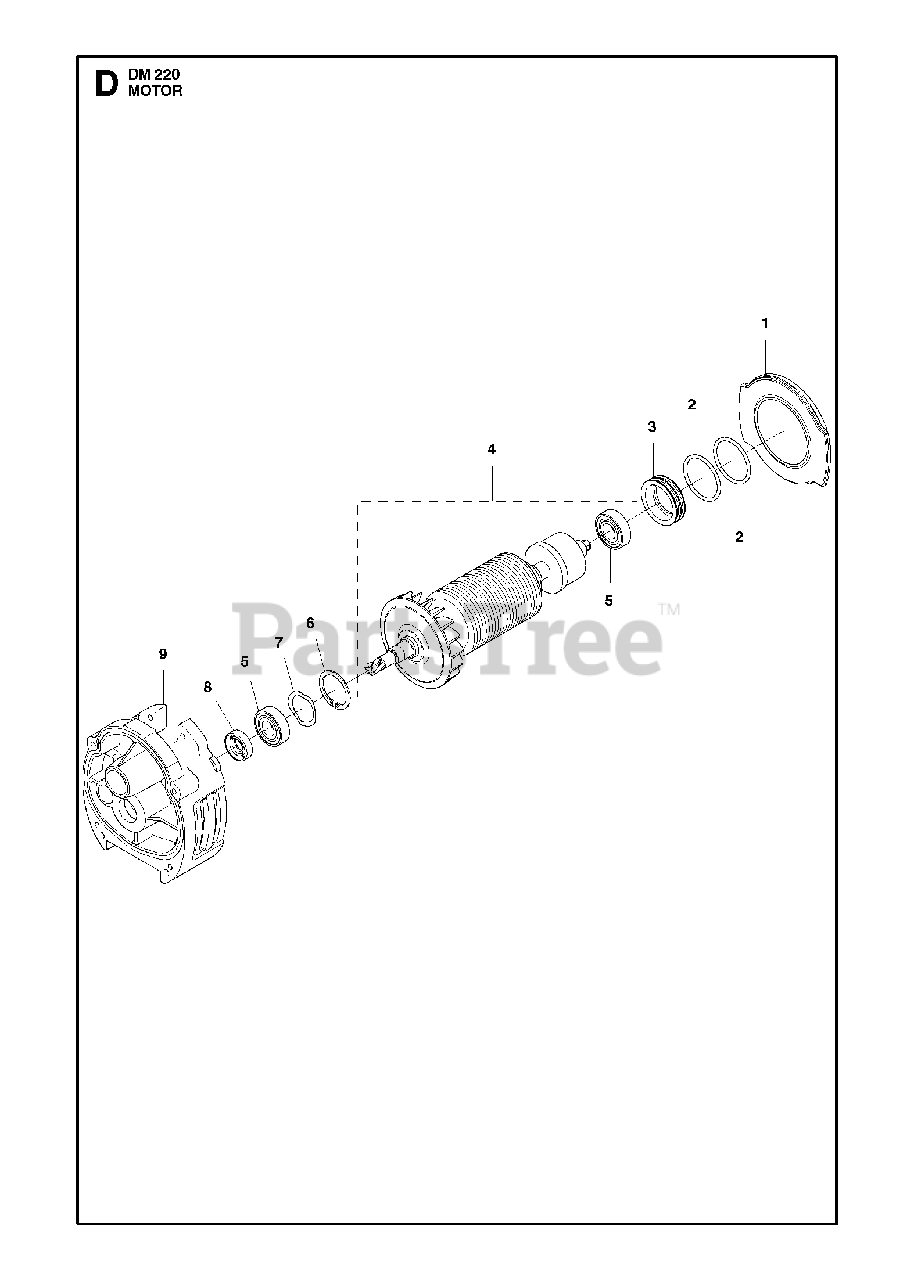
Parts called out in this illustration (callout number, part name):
1	AIR CONDUCTORValid before S/N 20153300021
3	BEARING SUPPORT
5	BALL BEARING
7	SPRING WASHER
9	COVERValid before S/N 20153300021 and includes 586 91 91-01
